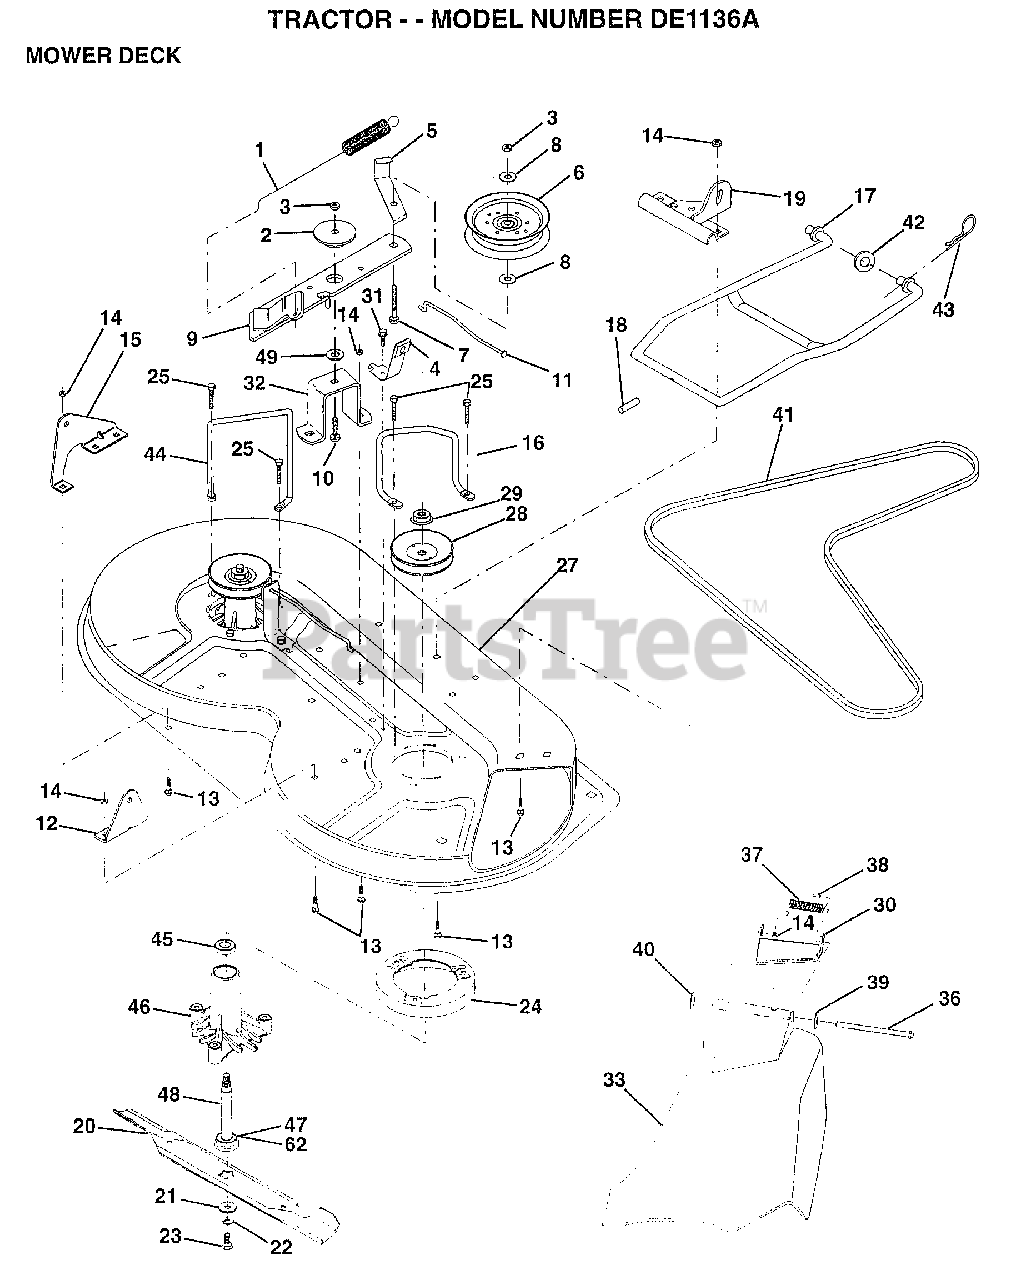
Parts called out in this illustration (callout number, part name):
1	SPRING CLUTCH MWR
2	SPACER RETAINER
4	BRAKE ASM
5	IDLER BELT GUIDE
6	PULLEY IDLER
7	BOLT
8	WASHER
10	BOLT.3/8-14X1.25
11	BRAKE ROD
12	"BRKT,LIFT REAR"
13	BOLT
15	"BRKT,LIFT REAR LH"
16	"KEEPER-BELT,RH"
17	MOWER LINK STAB
18	"PIN,GROOVE"
19	"BRKT,LINK STABILI"
20	"BLADE.36"" HIPERF"
21	WASHER.HARD.BLADE
23	BLADE BOLT
24	STRIPPER RND MWR
25	"SCREW-THD ROLL,WA"
27	"HOUSING-MOWER,36"""
28	PULLEY.MAND.36/46
31	SCREW LT
32	"SUPT,IDLER ARM"
36	HINGE ROD
37	SPRING TORSION
38	CAP-SLEEVE LT
39	WASHER
40	NUT PUSH M
41	V-BELT.PRIM.78.5.
43	RETAINER.SPRING
44	KEEPER BELT LH
45	BEARING
46	HSG ASM MANDREL
47	BEARING.BALL
49	HARDENED WASHER
62	WASHER.FELT.
